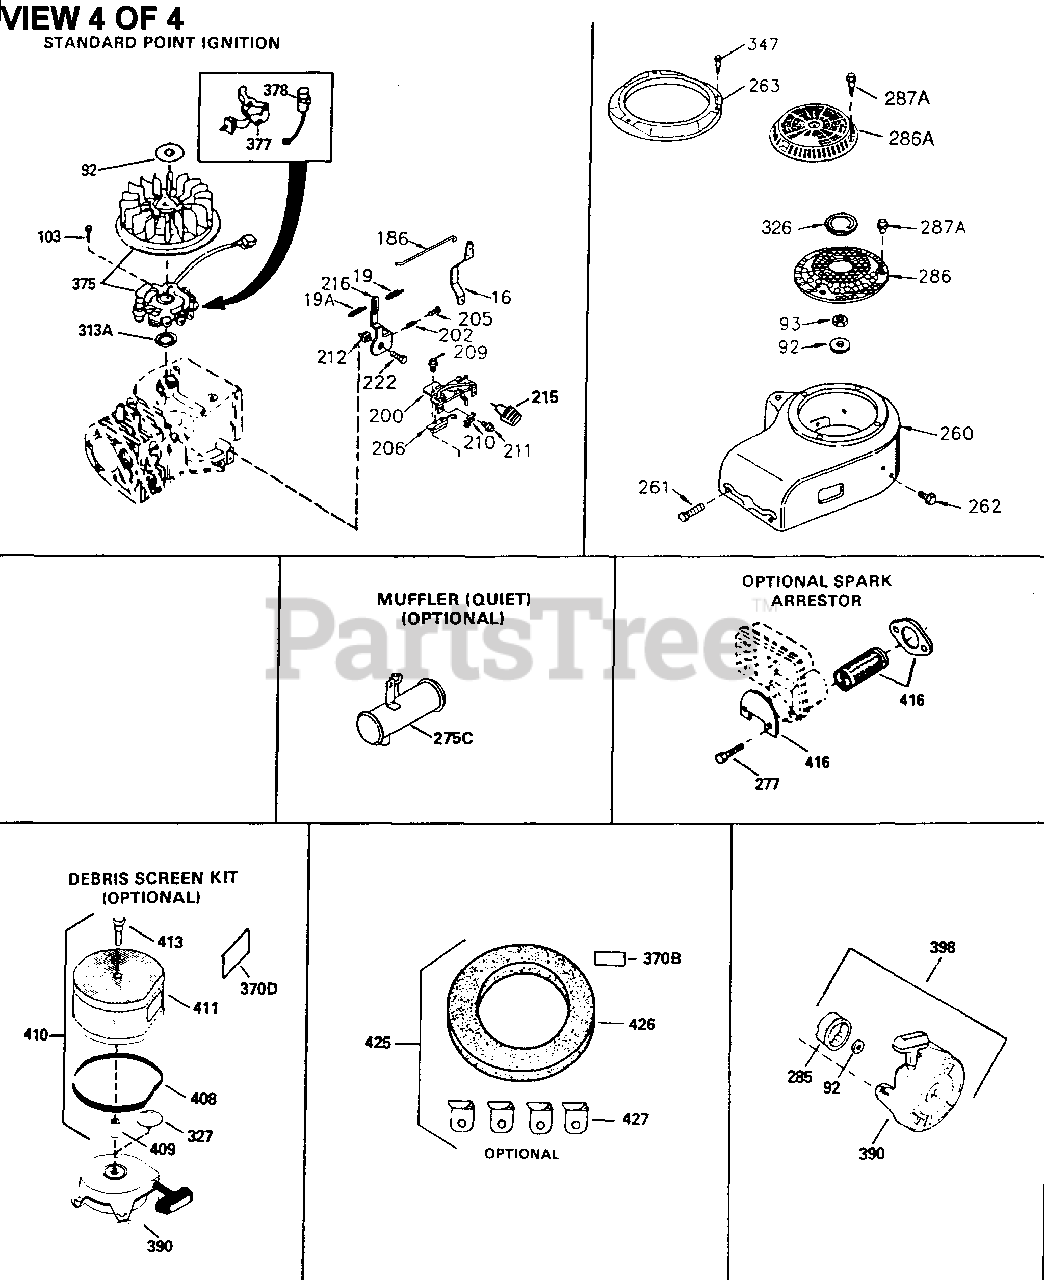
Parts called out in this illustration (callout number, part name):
16	Governor Lever
19A	Extension Spring
19A	Control Spring
64	Screw, T-30, 1/4-20 x 1/2"
92	Lock Washer
93	Flywheel Nut
103	Screw, Torx T-15, 10-24 x 1"
186	Governor Link
200	Control Bracket
202	Compression Spring
205	Screw, 6-32 x 21/32"
209	Screw, 10-24 x 9/16"
210	Conduit Clip
211	Screw, 10-32 x 3/8"
212	Bushing
216	R.P.M. Adj. Lever Incl. 19A, 212, 22 2 & 239
222	Screw, 10-32 x 1/2"
251A	Nut & Lock Washer, 1/4-20
260	Blower Housing
261	Screw, 5/16-18 x 3/4"
263	Trim Ring
285	Cup & Screen
292	Fuel Line Clamp
322A	Connector Body
326	Screen Plug
347	Screw, 10-32 x 9/16"
370B	Decal - Important Lubrication - SAE 3
